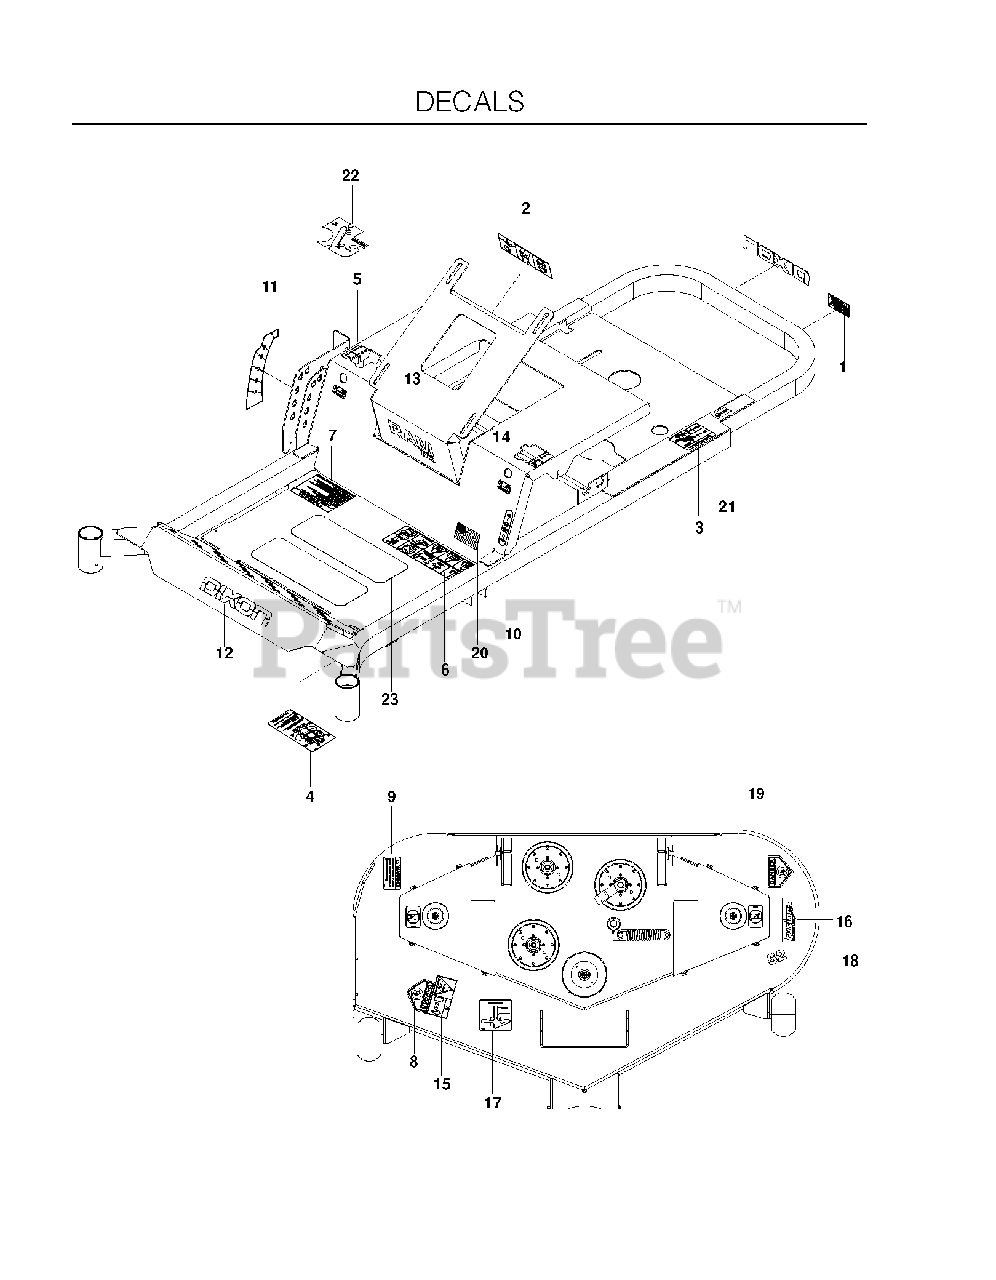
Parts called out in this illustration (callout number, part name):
1	DECAL, PROP. 65
2	DECAL, BATTERY
3	DECAL, DO NOT MOUNT
4	DECAL, SERVICE
5	DECAL, MOTION CONTROL
6	DECAL, SAFETY WARNING
7	DECAL, WARNING
8	DECAL, CPSC
9	DECAL, CAUTION
10	DECAL, PARK BRAKE
11	DECAL, HEIGHT
13	DECAL, RAM ZTR, 2008
14	DECAL, TRACKING
15	DECAL, EURO SEVERING
16	DECAL, FUSION
17	DECAL, BELT ROUTING
18	DECAL, 48
19	DECAL, NO STEP
20	DECAL, FLAG
21	DECAL, WARNING SPARK ARRESTOR
22	DECAL, CONTROLS PANEL, DIX
23	ANTI-SKID PAD
